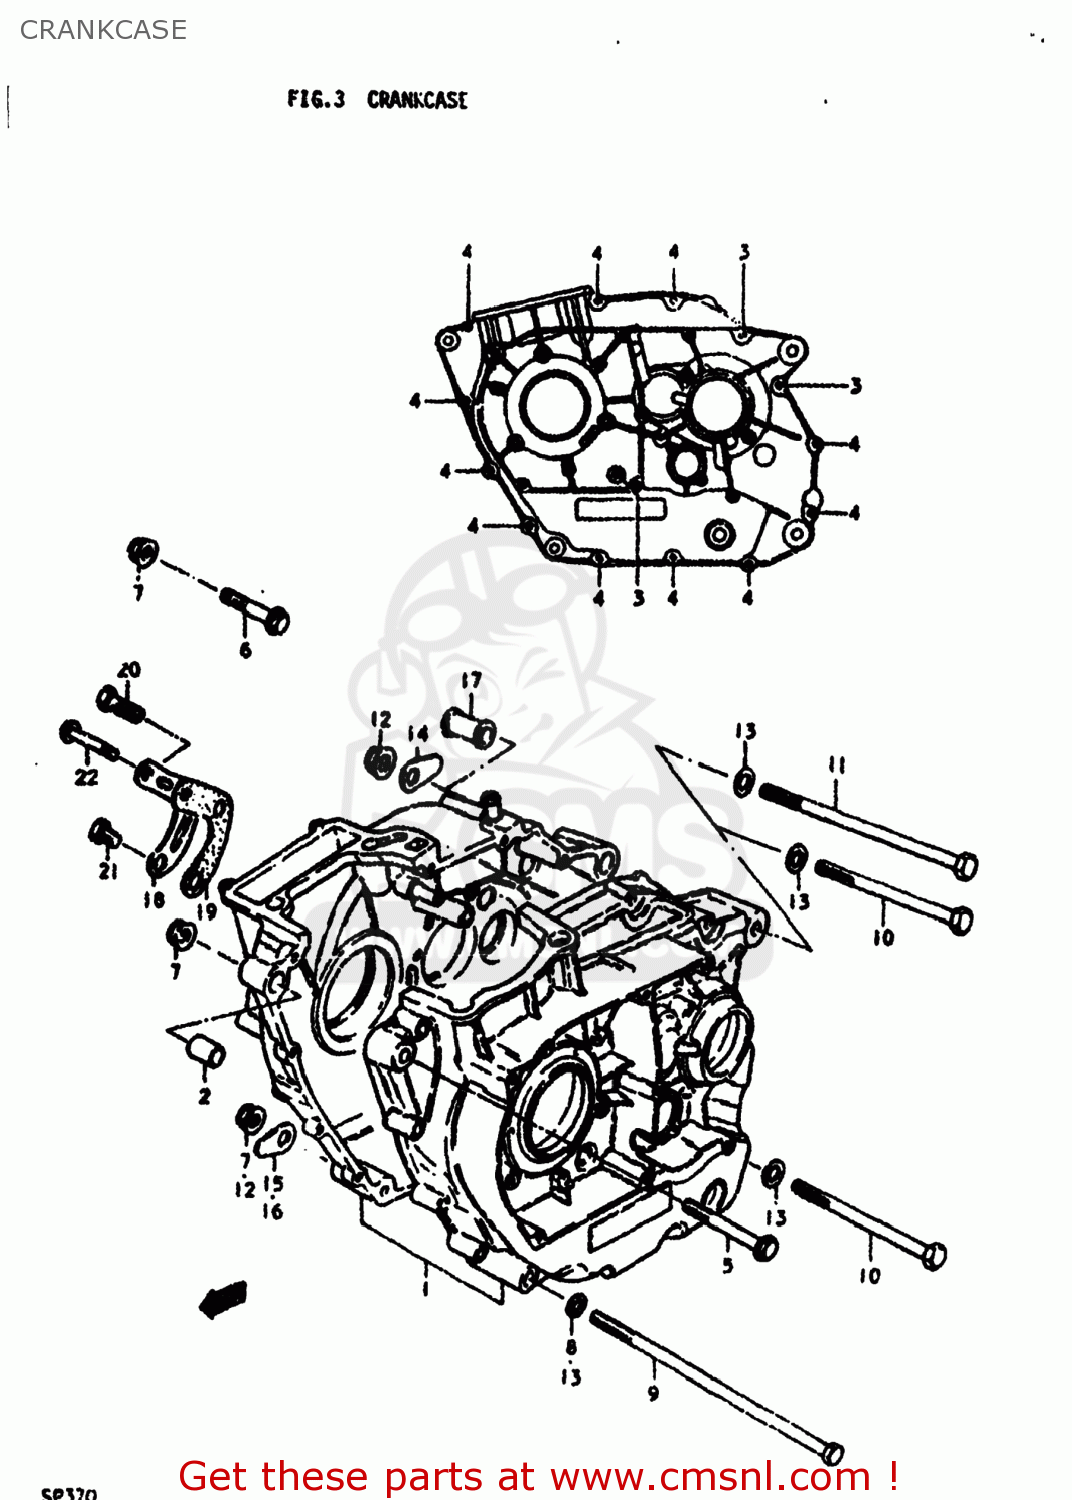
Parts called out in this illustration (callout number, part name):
1	CRANKCASE SET
2	PIN
3	SCREW
4	SCREW (6X35)
5	BOLT (8X70)
6	BOLT
7	NUT
8	WASHER
9	BOLT
10	BOLT 10X115
11	BOLT 10X155
12	NUT
13	WASHER
14	WASHER
15	WASHER
16	WASHER
17	SPACER
18	CAP,OIL GALLERY
19	GASKET,OIL GALLERY (MCA)
20	BOLT UNION
21	PLUG
22	BOLT
